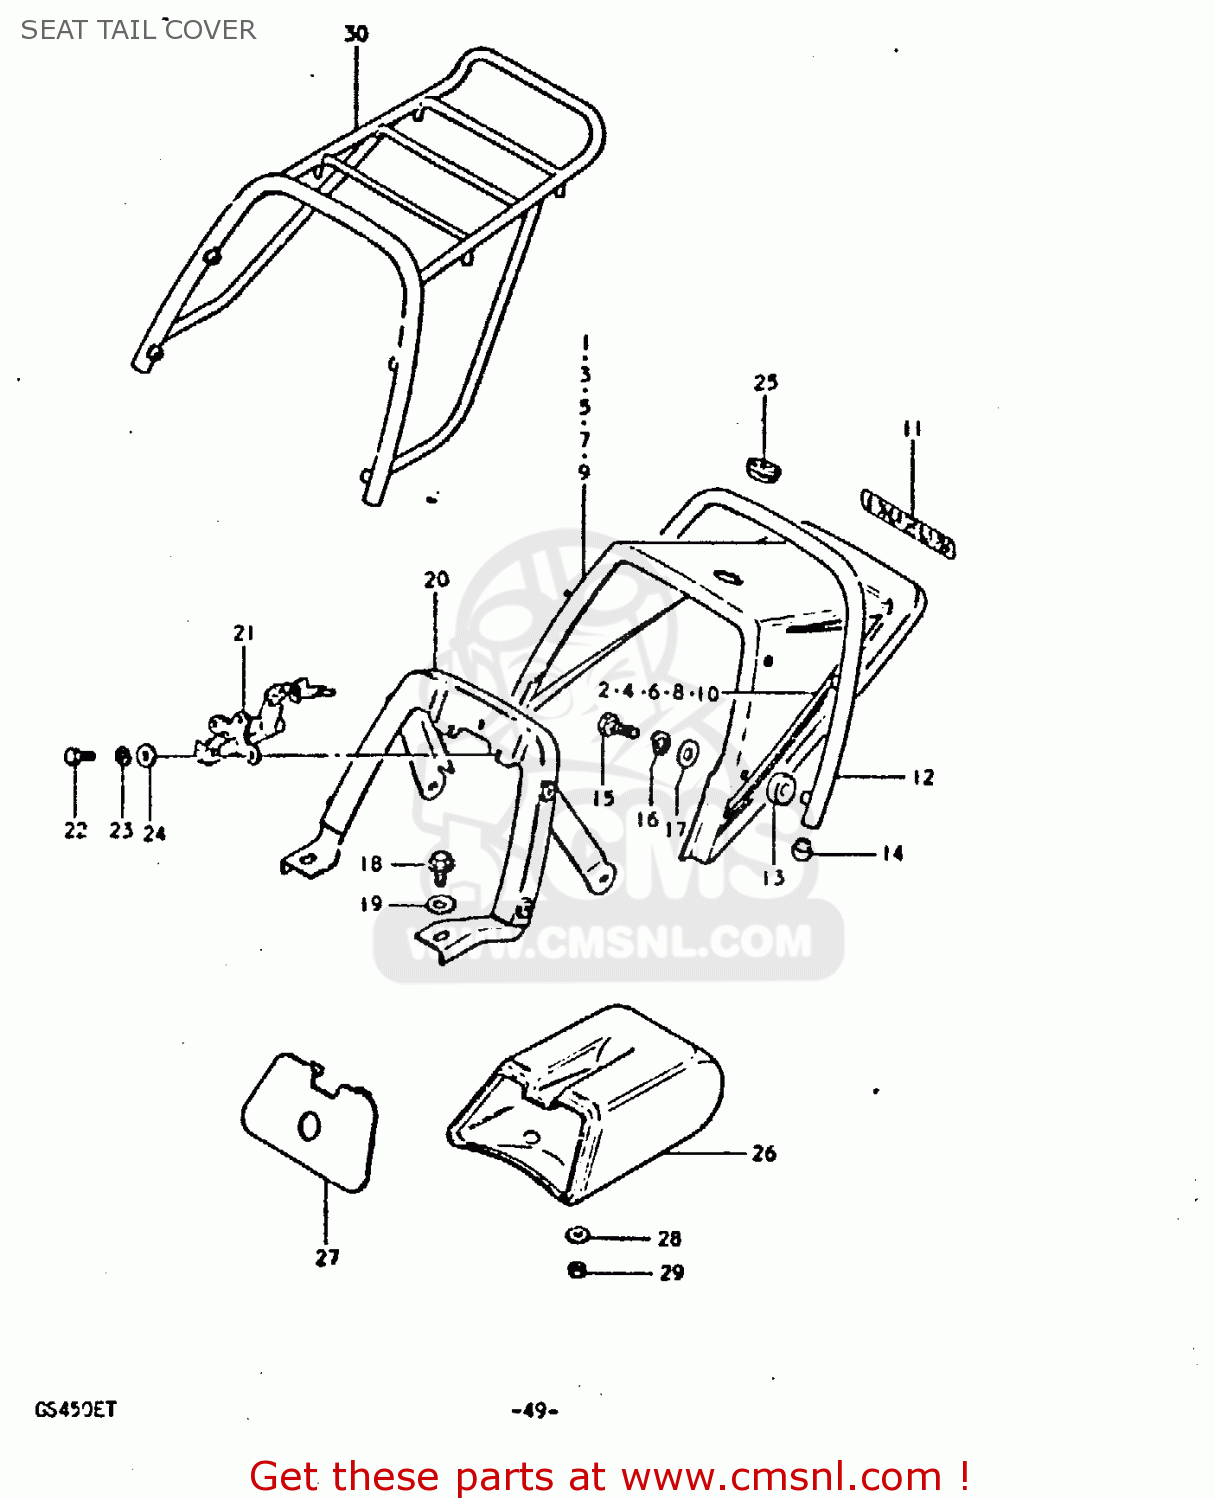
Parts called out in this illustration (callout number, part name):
1	COVER,SEAT TAIL
2	TAPE SET
3	COVER,SEAT TAIL
4	TAPE SET
5	TAIL COVER, SEAT (BLUE)
6	TAPE SET
7	COVER,SEAT TAIL
8	TAPE SET
11	EMBLEM
12	HANDLE,PILLION RIDER
13	CUSHION
14	END,SHEET HANDLE
15	BOLT (8X30)
16	LOCK WASHER
17	WASHER
18	BOLT
19	WASHER (8.7X22X2)
20	BRACKET, SEAT TAIL COVER
21	LOCK SET
22	BOLT
23	LOCK WASHER
24	WASHER
25	GROMMET,SEAT LOCK HOLE
26	BOX, SEAT TAIL
27	LID,SEAT TAIL BOX
28	WASHER
29	NUT 6MM
30	CARRIER
